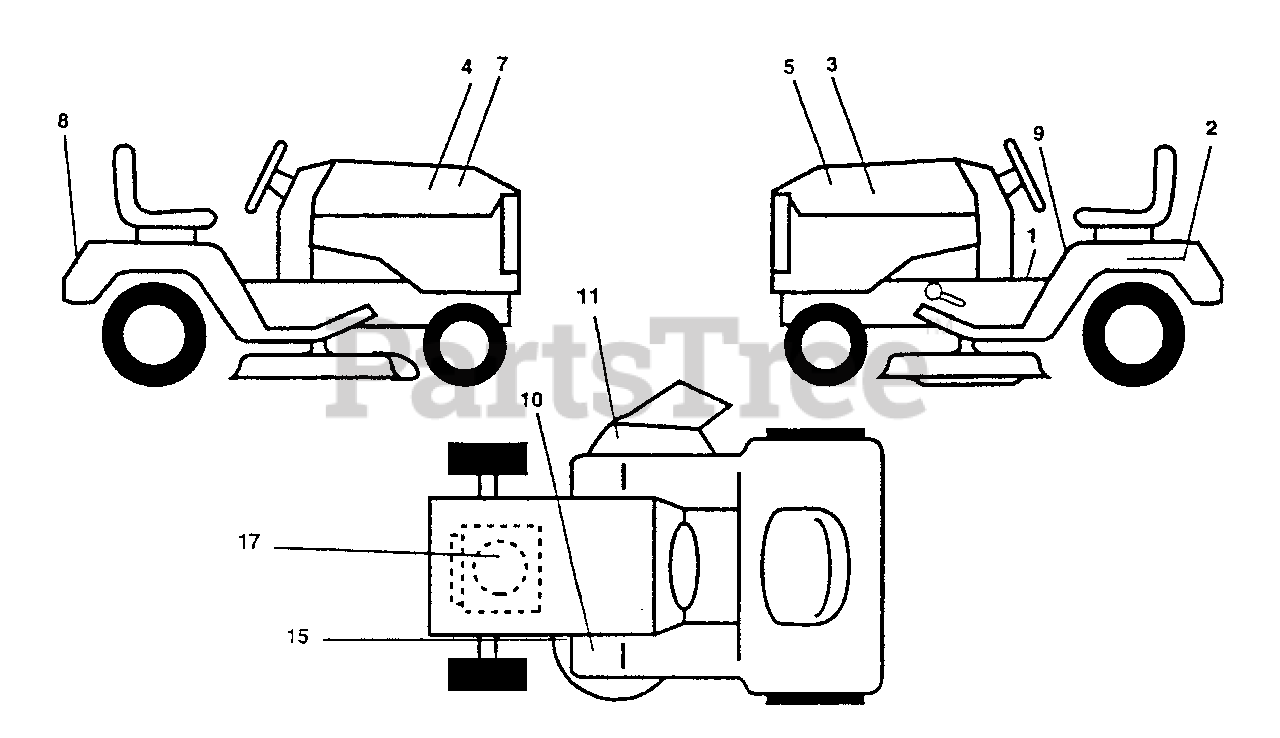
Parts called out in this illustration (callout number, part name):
1	Decal Instruction Dash Eng/fr
2	Decal Caution Battery Fr/ger
3	Decal Hood LH
4	Decal Hood RH
5	Decal Ins Hd LH
7	Decal Ins Hd RH
8	Decal Fender Logo
9	Decal Caution Fender Eng/fr
10	Decal Clutch/brake Eng/fr
11	Decal Warning Multi-Language
15	Decal V-Belt Schematic
17	Decal HP Engine
